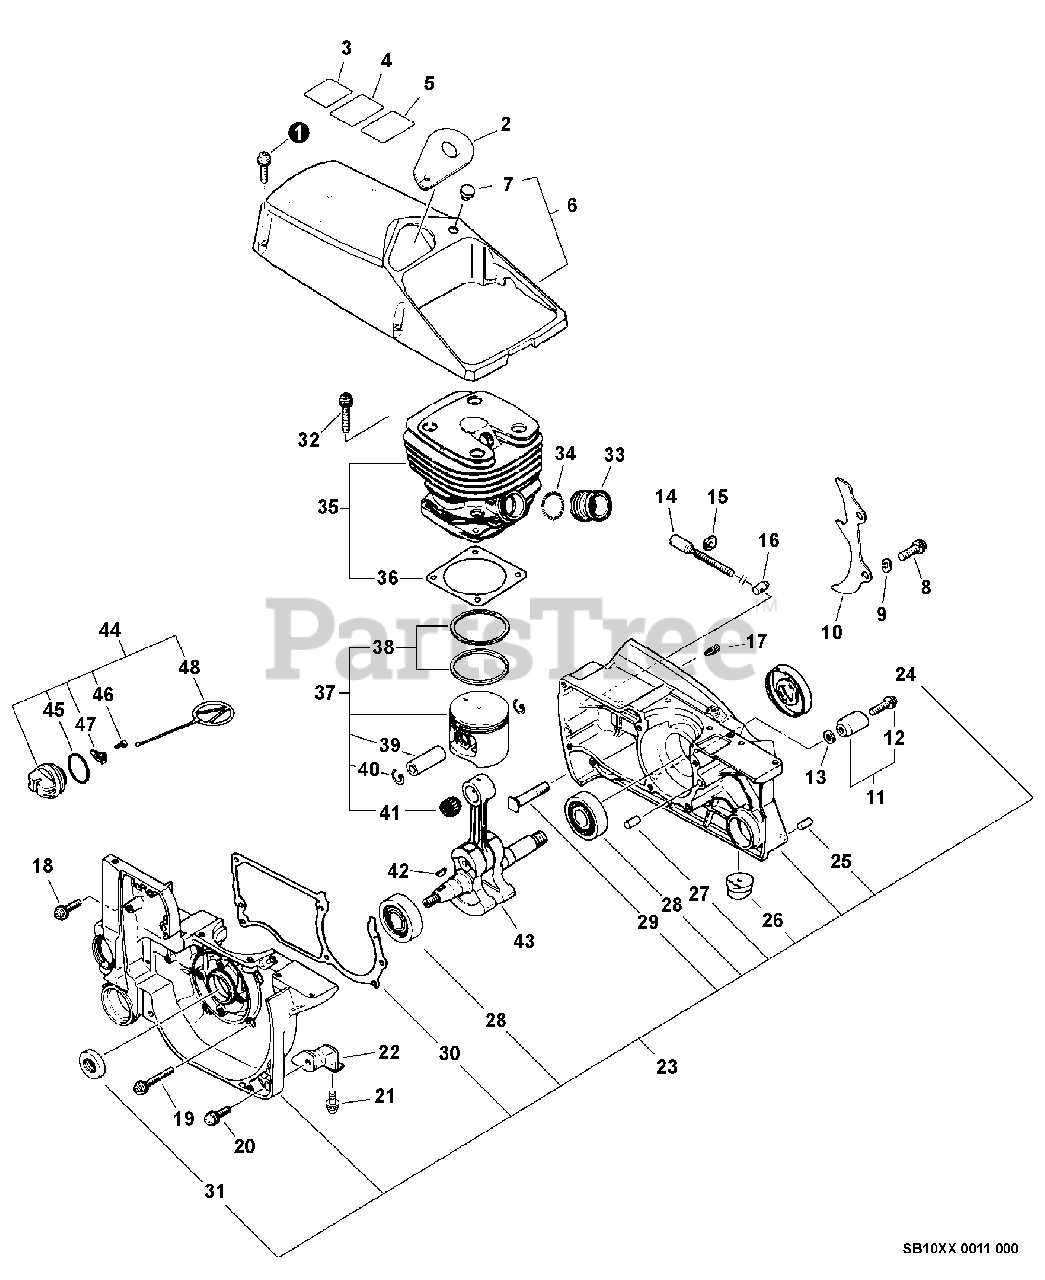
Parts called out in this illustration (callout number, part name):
1	SCREW - 5X20
2	PLATE, GUIDE
3	LABEL - KICK BACK
4	LABEL - BAR & CHAIN
5	LABEL - KICK BACK
6	ENGINE COVER KIT - GRAY
8	SCREW - 6X20
9	LOCKWASHER - 6
11	CHAIN CATCHER KIT
12	SCREW - 5X20
13	WASHER - 5
14	SCREW, TENSIONER
16	TENSIONER, CHAIN
17	VENT, TANK
18	SCREW - 5X20
19	SCREW - 5X35
20	SCREW - 5X14
21	SCREW - 5X14
23	CRANKCASE KIT - GRAY
24	SEAL, OIL
25	PIN - SPRING -- 5X10
27	PIN - LOCATING
28	BEARING, BALL - 6203
29	STUD, GUIDE BAR
30	GASKET, CRANKCASE
31	SEAL, OIL
32	SCREW - 6X25
33	ADAPTOR, INTAKE
35	CYLINDER ASSY
36	GASKET, CYLINDER
37	PISTON KIT
38	RING, PISTON
39	PIN, PISTON
40	RING, RETAINING
41	BEARING, NEEDLE
43	CRANKSHAFT ASSY
44	CAP ASSY
45	O-RING - 25
46	SCREW - 3X8
47	RETAINER
48	CONNECTOR, CAP
